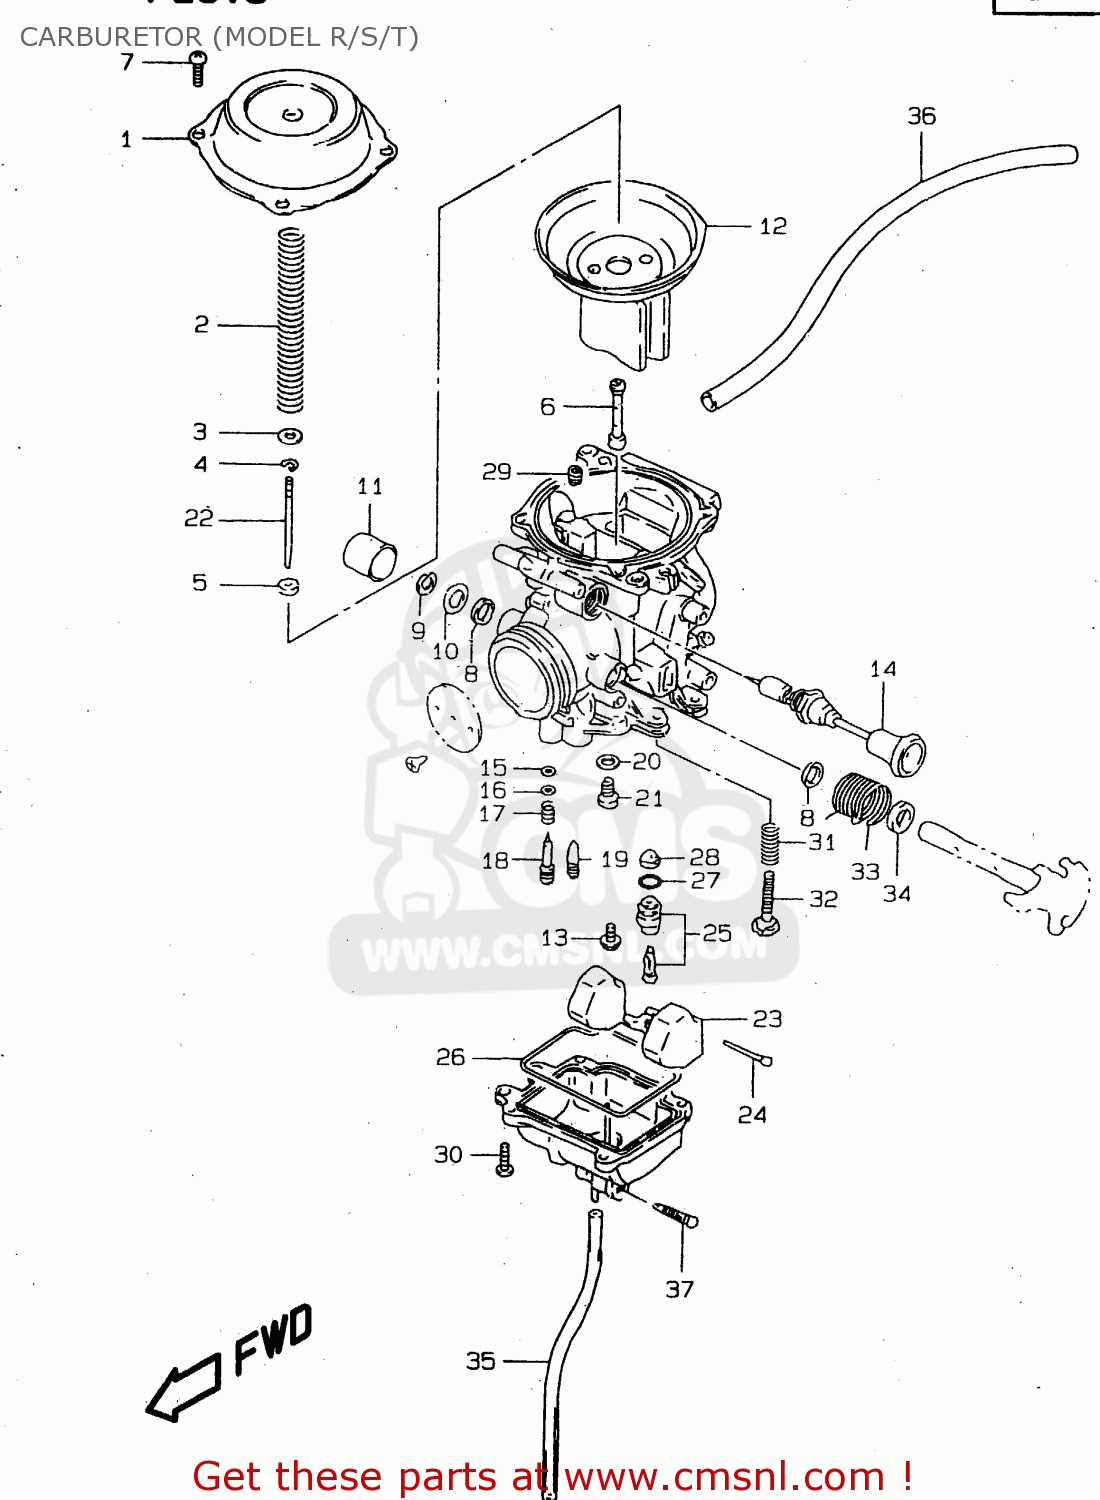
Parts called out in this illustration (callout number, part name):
1	COVER,DIAPHRAGM
2	SPRING
3	RING
4	CLIP
5	RING
6	JET,NEEDLE(P-5)
7	SCREW
8	SEAL,THROTTLE SHAFT
9	E RING
10	GASKET,THROTTLE SHAFT (NAS)
11	CAP
12	DIAPHRAGM ASSY
13	SCREW
14	PLUNGER ASSY
15	O RING,PILOT AIR SCREW
16	WASHER
17	SPRING
18	SCREW,PILOT
19	JET(40)
20	WASHER,NEEDLE NOZZLE
21	JET,MAIN(110)
22	NEEDLE,JET
23	FLOAT
24	PIN,FLOAT
25	VALVE ASSY,NEEDLE
26	O RING,FLOAT CHAMBER
27	O-RING,NEEDLE VALVE
28	FILTER
29	JET,AIR(140)
30	SCREW
31	SPRING,THROTTLE SCREW
32	SCREW,THROTTLE STOP
33	SPRING
34	RING
35	HOSE(3X5X650)
36	HOSE(5X8.2X600)
37	SCREW,DRAIN
